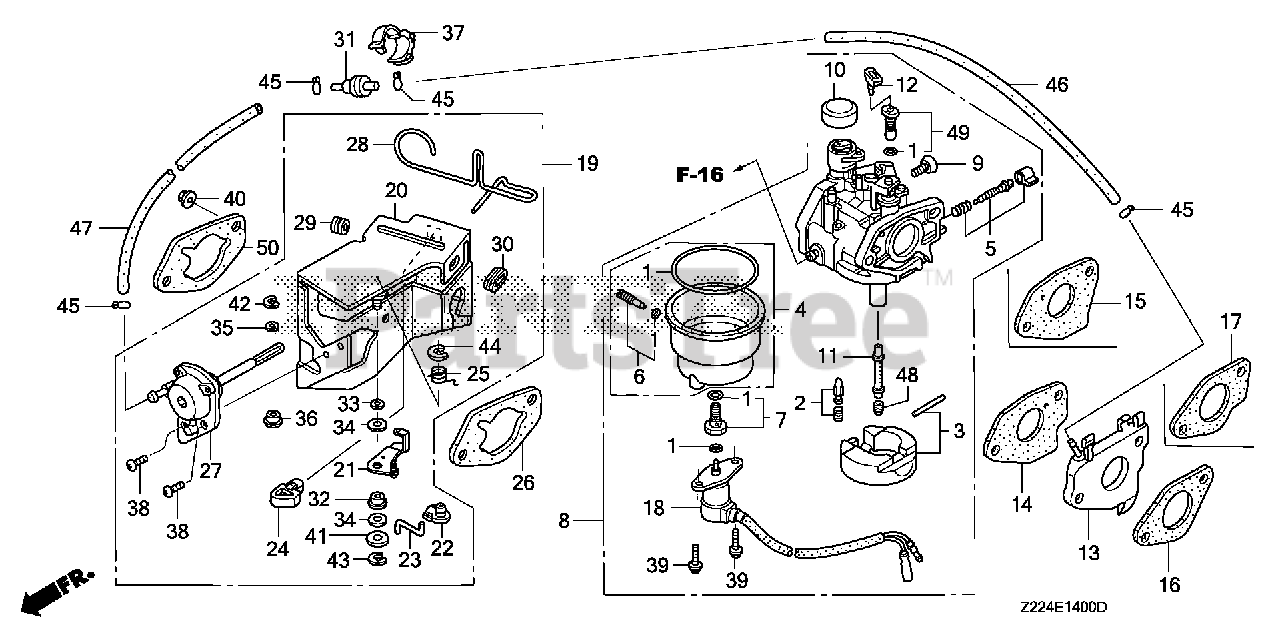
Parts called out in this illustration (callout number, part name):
1	GASKET SET
2	VALVE SET, FLOAT
4	CHAMBER SET, FLOAT
6	SCREW SET, DRAIN (CARBURETOR NO.)
8	CARBURETOR ASSY. (BE89J A)
9	SCREW, THROTTLE STOP
10	CAP, CHOKE DUST
11	NOZZLE, MAIN
12	COLLAR, SETTING
13	INSULATOR, CARBURETOR
15	GASKET, CARBURETOR
15	GASKET, CARBURETOR (NINGBO SIL GASKET)
17	GASKET, INSULATOR (NINGBO SIL GASKET)
17	GASKET, INSULATOR
18	VALVE ASSY., SOLENOID
19	STAY ASSY., MANUAL CHOKE (NOT AVAILABLE)
20	STAY, SOLENOID
21	LEVER, CHOKE
22	JOINT, ROD
23	ROD, CHOKE
24	STOPPER, CHOKE ROD
25	SPRING, MANUAL CHOKE
26	GASKET, AIR CLEANER
27	DIAPHRAGM ASSY.
28	ROD, CHOKE CONTROL
29	GROMMET, CHOKE ROD
30	GUIDE, CHOKE ROD
31	VALVE, DASHPOT CHECK
32	BUSH, ARM PIVOT
33	WASHER, CHOKE LEVER
34	SEAL, CHOKE LEVER
35	WASHER, THRUST (2.7X8)
36	COLLAR, LEVER
37	CLIP, WIRE HARNESS
38	SCREW, PAN (5X12)
39	SCREW-WASHER (5X12)
40	NUT, FLANGE (6MM)
41	WASHER, PLAIN (5MM)
42	E-RING (2MM)
43	E-RING (4MM)
44	E-RING (7MM)
45	CLIP, TUBE (B7)
46	BULK HOSE, VACUUM (3.5X8000) (3.5X75)
47	BULK HOSE, VACUUM (3.5X8000) (3.5X130)
48	JET, MAIN (#98) (CARBURETOR NO.)
48	JET, MAIN (#100) (CARBURETOR NO.)
48	JET, MAIN (#102) (CARBURETOR NO.)
49	JET SET, PILOT (#45)
50	SPACER, CARBURETOR
